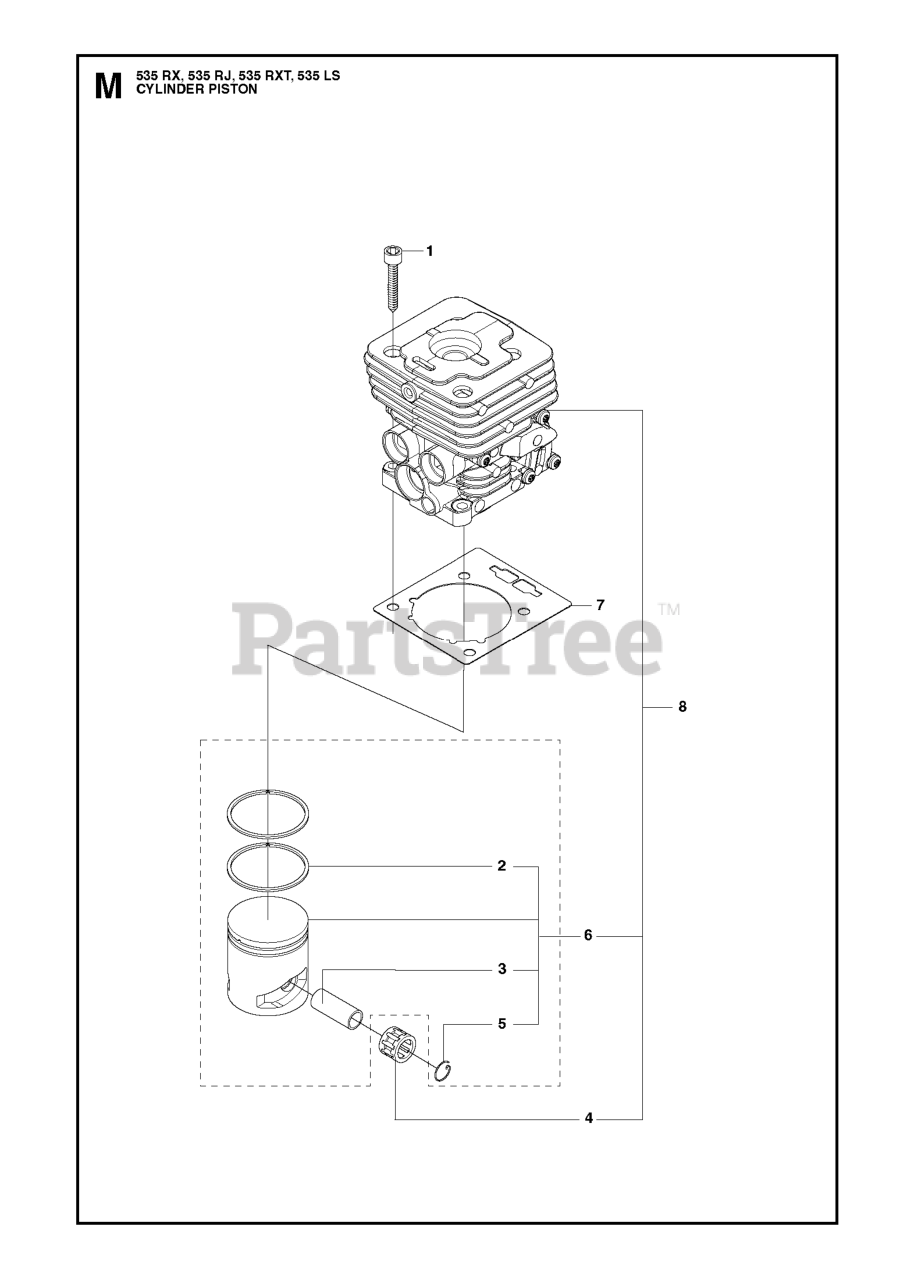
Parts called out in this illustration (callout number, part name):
1	SCREW MC6S 5X25
2	PISTON RING
3	PISTON BOLT
4	SUPPORT BUSHING
5	LOCKING RING
6	PISTON ASSY
7	GASKET CYLINDER
8	%CYLINDER CPL
